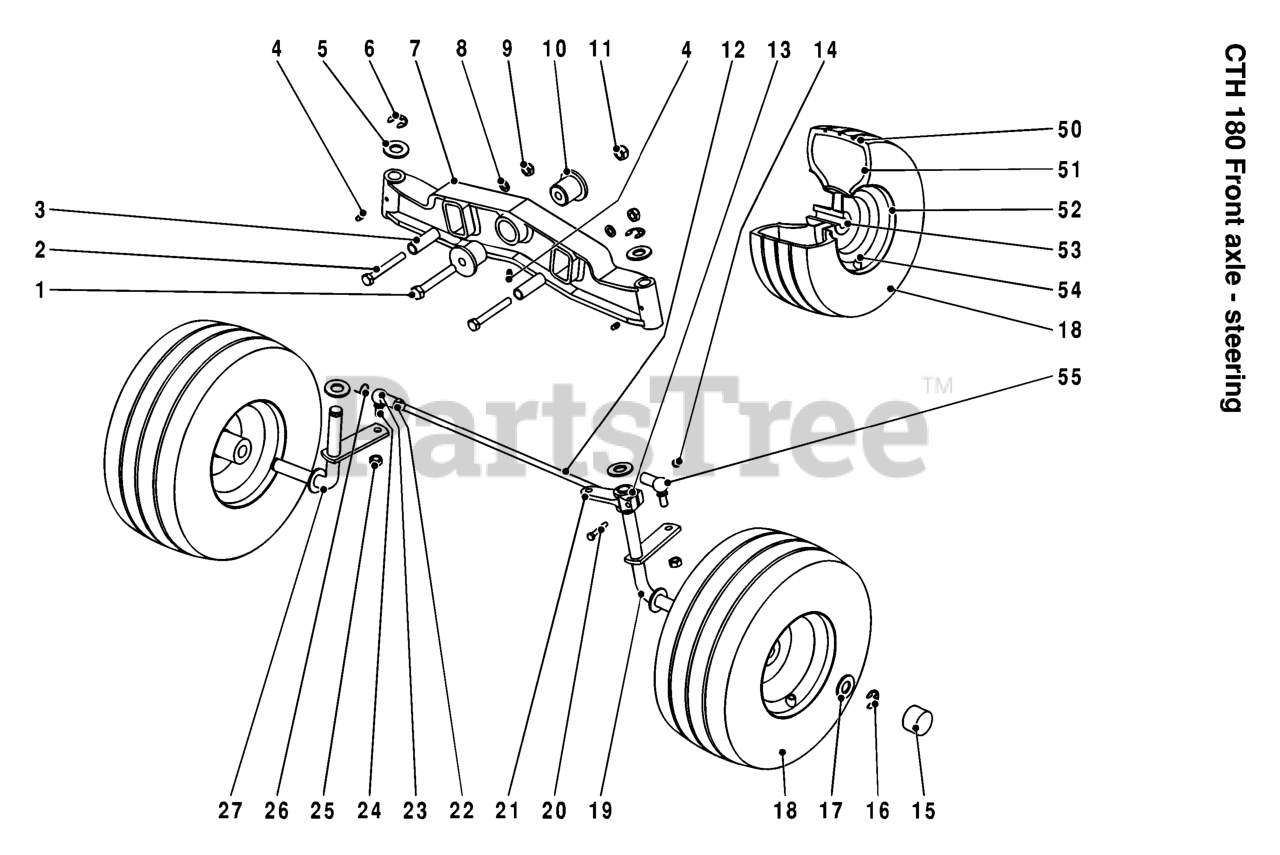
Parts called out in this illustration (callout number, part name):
6	RETAINING RING
8	REPL BY 735 11 73-50
14	Blocking nut M 6 Z
16	RETAINING RING
21	BALL JOINT
23	BALL JOINT
24	BALL JOINT
50	REPL BY 532 10 62-30
